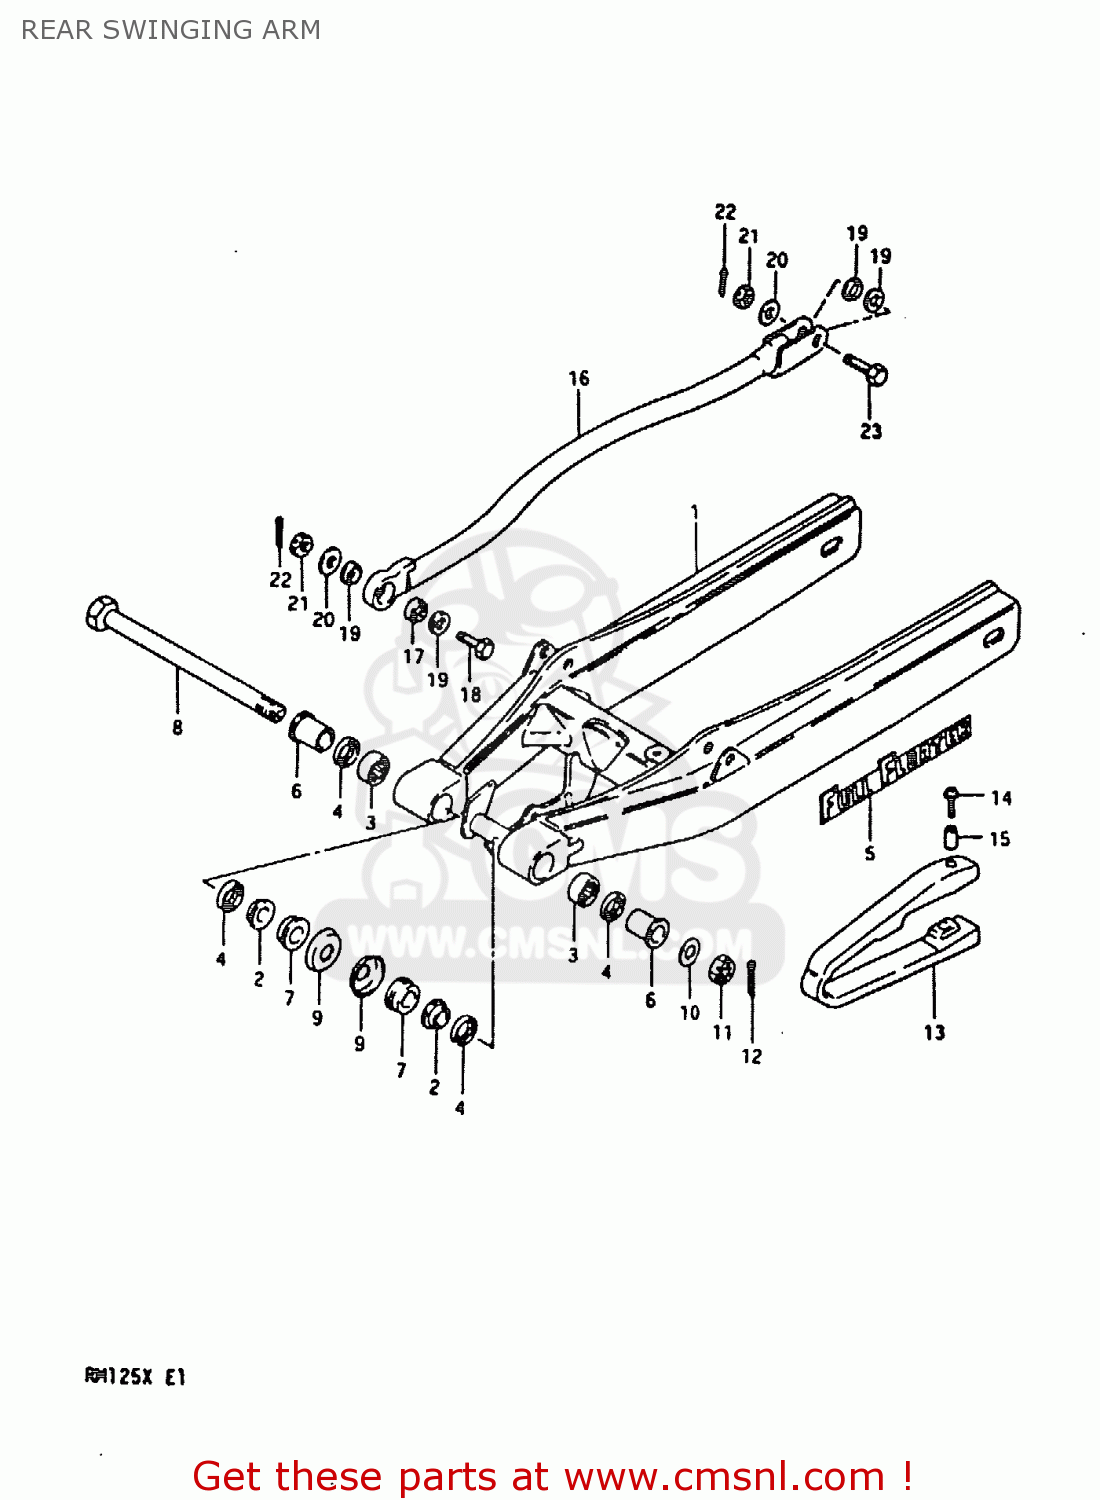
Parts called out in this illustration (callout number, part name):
1	SWING ARM ASSEMBLY,REAR
2	BUSH,RR SWINGINGARM PIVOT
3	BEARING(20X27X20)
4	OIL SEAL
5	EMBLEM,SWING ARM
6	SPACER,RR SWGARM PIVOT
7	SPACER,RR SWGARM PIVOT INNER
8	SHAFT,RR SWINGINGARM PIVOT
9	COVER,RR SWGARM DUST SEAL
10	WASHER
11	NUT 14MM
12	COTTER PIN
13	BUFFER,CHAIN TOUCH DEFLECTOR
14	SCREW,CHAIN TOUCH DEFEND
15	SPACER (5.5X8X4)
16	LINK,REAR TORQUE
17	SPHERICAL BRNG,TORQUE LINK
18	BOLT 8X28
19	20
20	WASHER
21	NUT 8MM
22	PIN 20X20
23	BOLT 8X29.5
